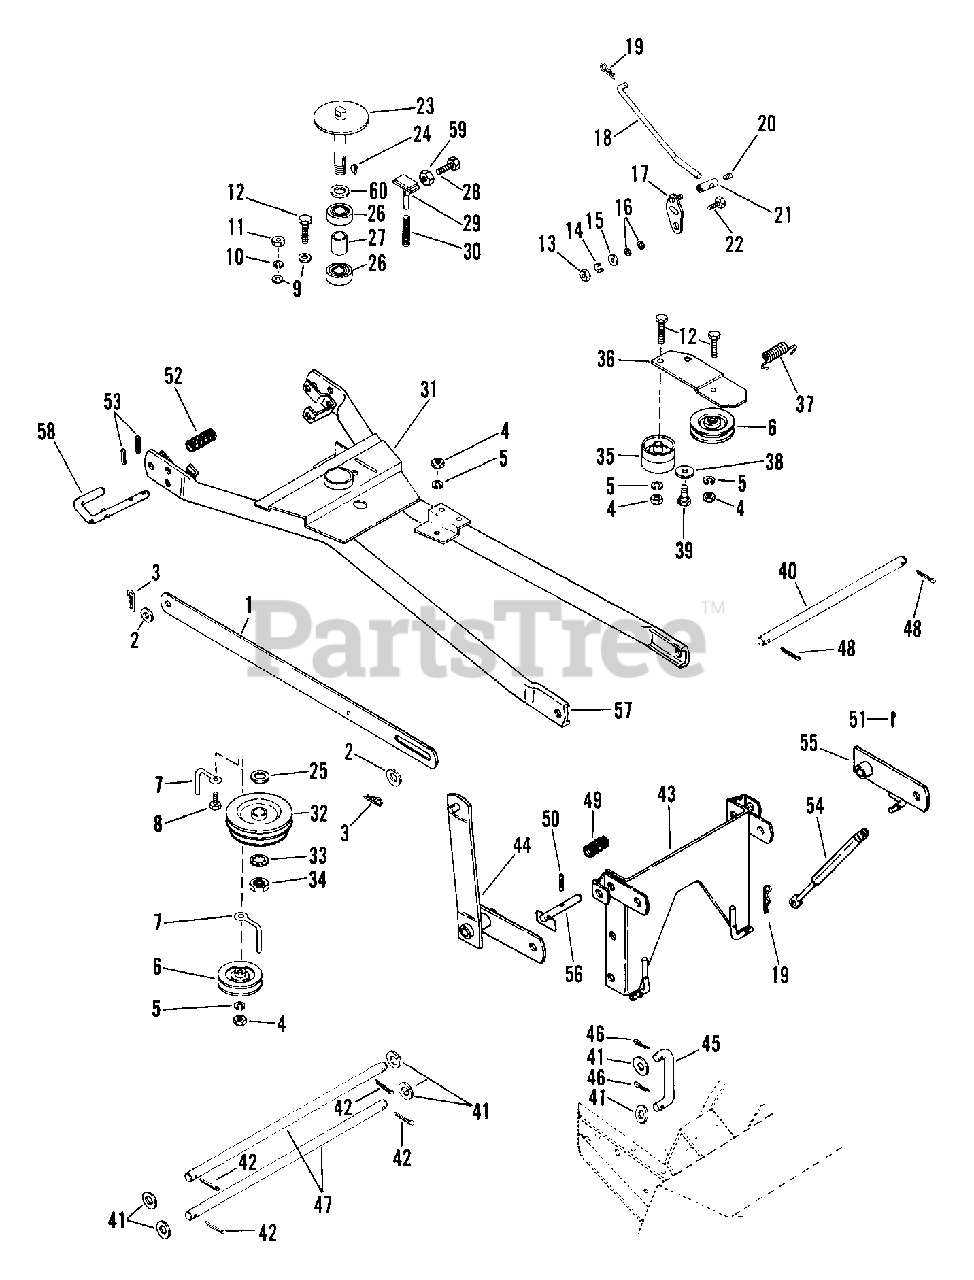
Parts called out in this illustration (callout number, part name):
1	LIFT STRAP
2	WSHR-FL-STL .531X1.062X.095 PL
3	PIN-HAIR INT .14X.4X2.75
4	NUT-HEX .375-16
5	WSHR-LK .375X.115 HVY PL
6	IDLER-V 3.06 X .38
7	BELT FINGER
8	BLT-HEX .31-18X1.00 PL GR 2
9	WSHR-FL-STL .38X.875X.083 PL
10	WSHR-LK .312X.097 PL HVY
11	NUT-HEX .312-18
12	BLT-HEX .38-16X1.75 PL GR2
13	NUT-HEX .250-20 PL
14	WSHR-LK .250X.077 HVY PL
15	WSHR-FL-STL.312X.734X.065PL
16	WSHR-FL-STL .265X.500X.087 PL
17	BRAKE ACTUATOR
18	BRAKE ACTUATOR
19	PIN-HAIR INT .08X.18X1.18
20	SCR-SET .32-18X.38 SKHCUPNL OH
21	ROD ADAPTER
22	BLT-HEX .25-20X.75 PL GR5
23	SPINDLE SHAFT
24	KEY-WDRF .188X.75X.313 SAE 9
25	WSHR-FL-STL .781X1.250X.059 PL
26	BRG-BALL .750X1.781X.61
27	SPACER .765X1.000X1.252
28	SCR-SKH 10-24X1.25
29	PLUNGER
30	SG-COMP ??X.44X?? WLD 10
31	SPINDLE HOUSING
32	DOUBLE SHEAVE
33	WSHR-LK-INT .750X.050 MED
34	NUT-JAM .75-10 PL
35	IDLER-FLAT 2.25 X .38
36	IDLER ARM
37	SG-TENS .080X.73X3.06 WLD 20
38	WSHR-FL-STL .511X1.441X.125 PL
39	SHOULDER BOLT .50 X .281
40	MOUNT ROD
41	WSHR-FL-STL.656X1.312X.095 PL
42	PIN-COTR .15X1.50
43	PIVOT FRAME
44	LIFT BELLCRANK
45	LIFT LINK
46	PIN-COTR .12X1.0 PL
47	PIVOT ROD
48	PIN-ROLL .188X1.00
49	SG-COMP .072X.77X1.75
50	PIN-ROLL .125X.88
51	PIN-COTR .09X1.0 PL
52	SPRG, COMP .058X.65X2.13 WLD15
53	PIN-ROLL .125X.75
54	SG-GAS COMP .315X.75X10.00 120
55	LIFT LEVER
56	HITCH PIN
57	CARRIAGE FRAME
58	LATCH PIN
59	NUT-HEX 10-24 PL
60	WSHR-FL-STL .754X1.000X.032
